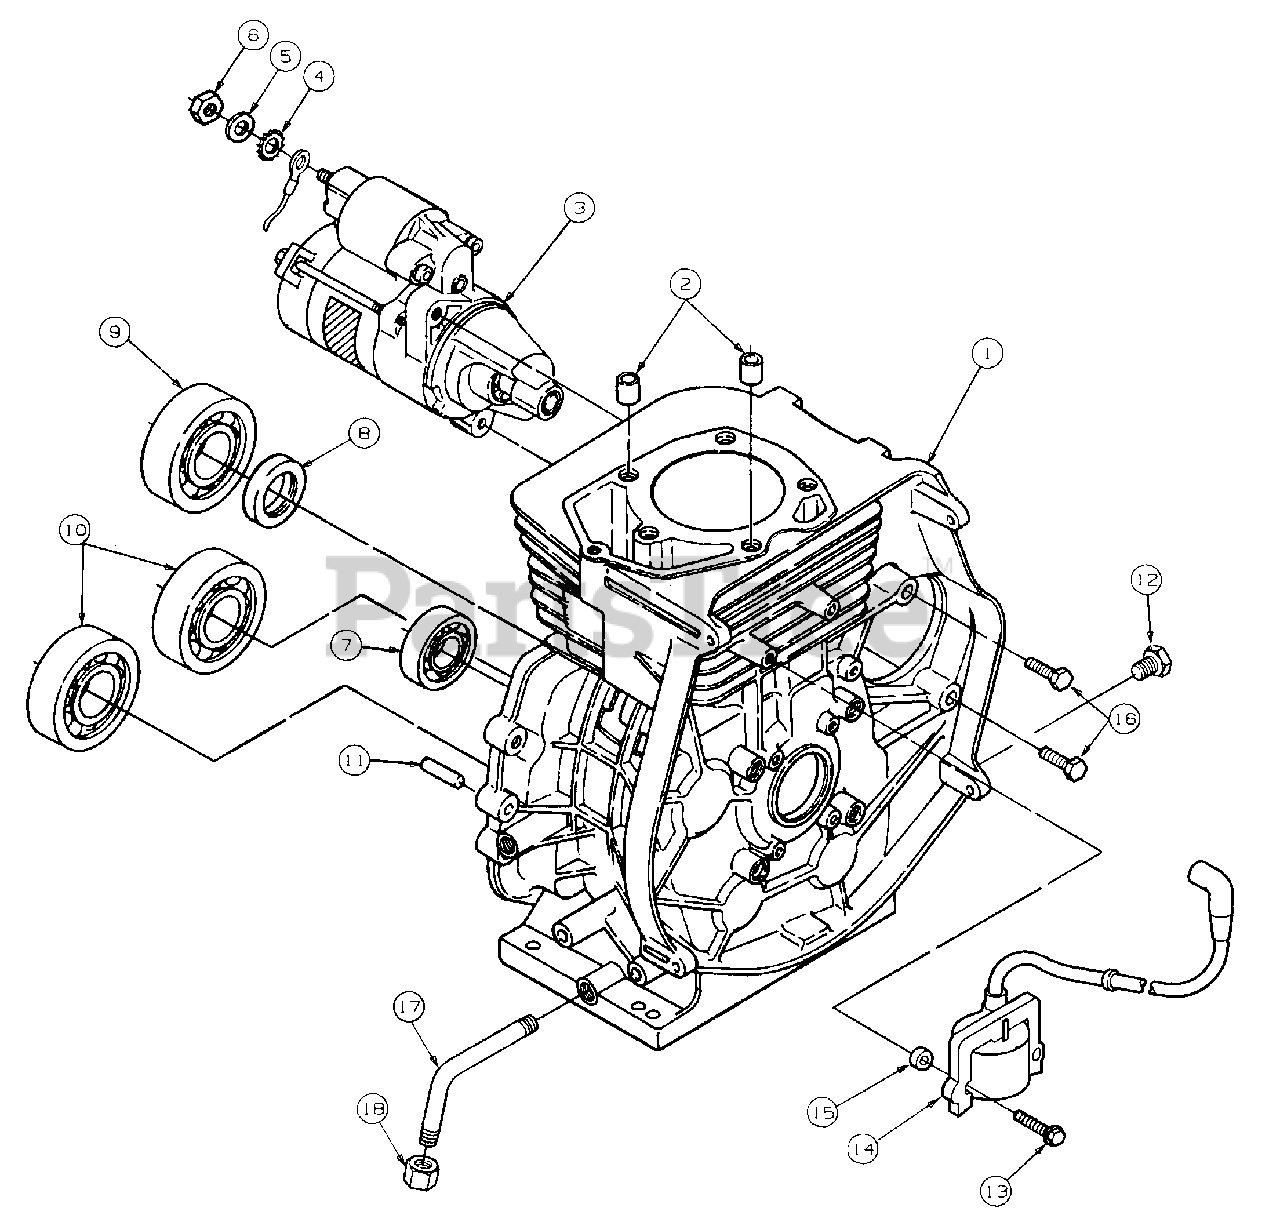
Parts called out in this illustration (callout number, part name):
1	Engine, Complete
2	Pin, Hollow Dowel
3	Starter
4	Washer, Lock, ET
5	Washer, Flat
7	Bearing, Camshaft
8	Seal, Crankshaft Oil
9	Bearing, Crankshaft
10	Bearing, Balancer Shaft
11	Pin, Alignment
12	Plug, Oil Drain
13	Screw, Pan Head M6 x 1 x 30 mm
14	Coil, Ignition
15	Spacer, Ignition Coil, M6 x 30 mm
16	Screw, Hex Head Cap, M8 x 1 x 40 mm
17	Pipe, Oil Drain
18	Cap, Oil Drain
